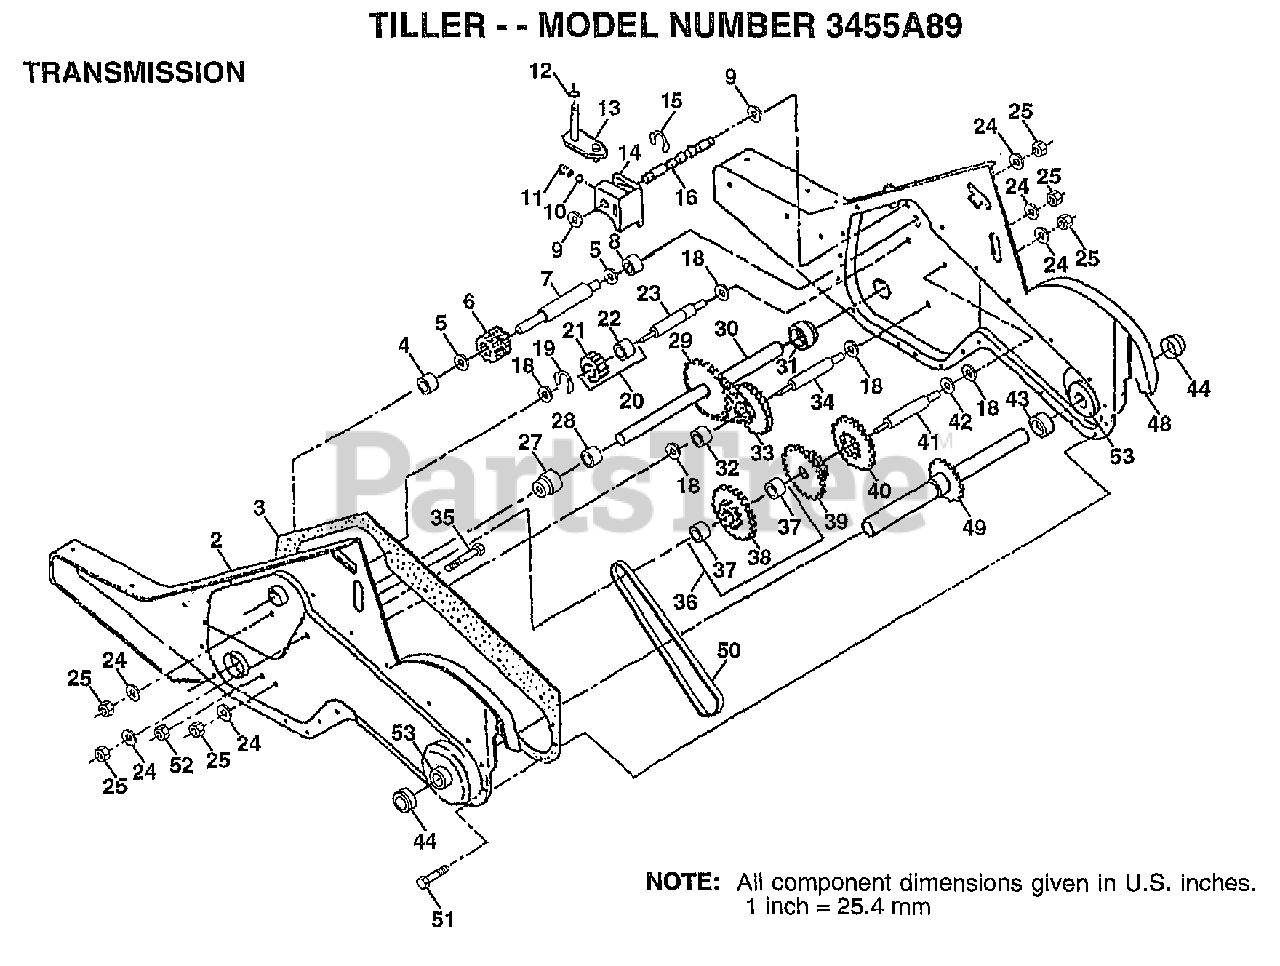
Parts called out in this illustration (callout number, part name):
2	GEARCASE LH W/BRG
3	GASKET TI
4	NEEDLE BRNG LT
5	"T, BEARING"
6	GEAR PINION INPUT
7	"SHAFT.INPUT.""D"""
8	"TI, BEARING"
9	WASHER SEAL
11	SPRING-SHIFT CRT
12	O-RING TI
13	BRACKET ASM SHIFT
14	SHIFT FORK TI
15	KLIP RING
16	SHAFT.SHIFTER
18	WASHER
19	KLIP RING
20	GEAR ASSY CRT
21	GEAR-REV IDLR CRT
22	NEEDLE BEARING TI
23	SHAFT CRT
24	LOCKWASHER
25	NUT.ASF.HEX.7/16
27	BEARING.SHAFT.LH.
28	BUSHING TI
29	CHAIN CRT
30	GROUND SHAFT ASSY
31	BEARING.SHAFT.RH.
32	SPACER TI
33	SPRCKT 8 GEAR CRT
34	SHFT 2ND RED. CRT
35	SCRW WHIZ LOK CRT
36	SPROCKET.ASM.W/BR
37	BEARING
39	GEAR TI
40	GEAR TI
41	REDUCTION SHFT TI
42	BRNG RACE
43	SPACER TI
44	SEAL ASM-OIL
48	GEARCASE RH W/BRG
49	TINE SHAFT
50	CHAIN.50 LINK TI
51	SCREW
52	NUT.HEX.5/16-18
